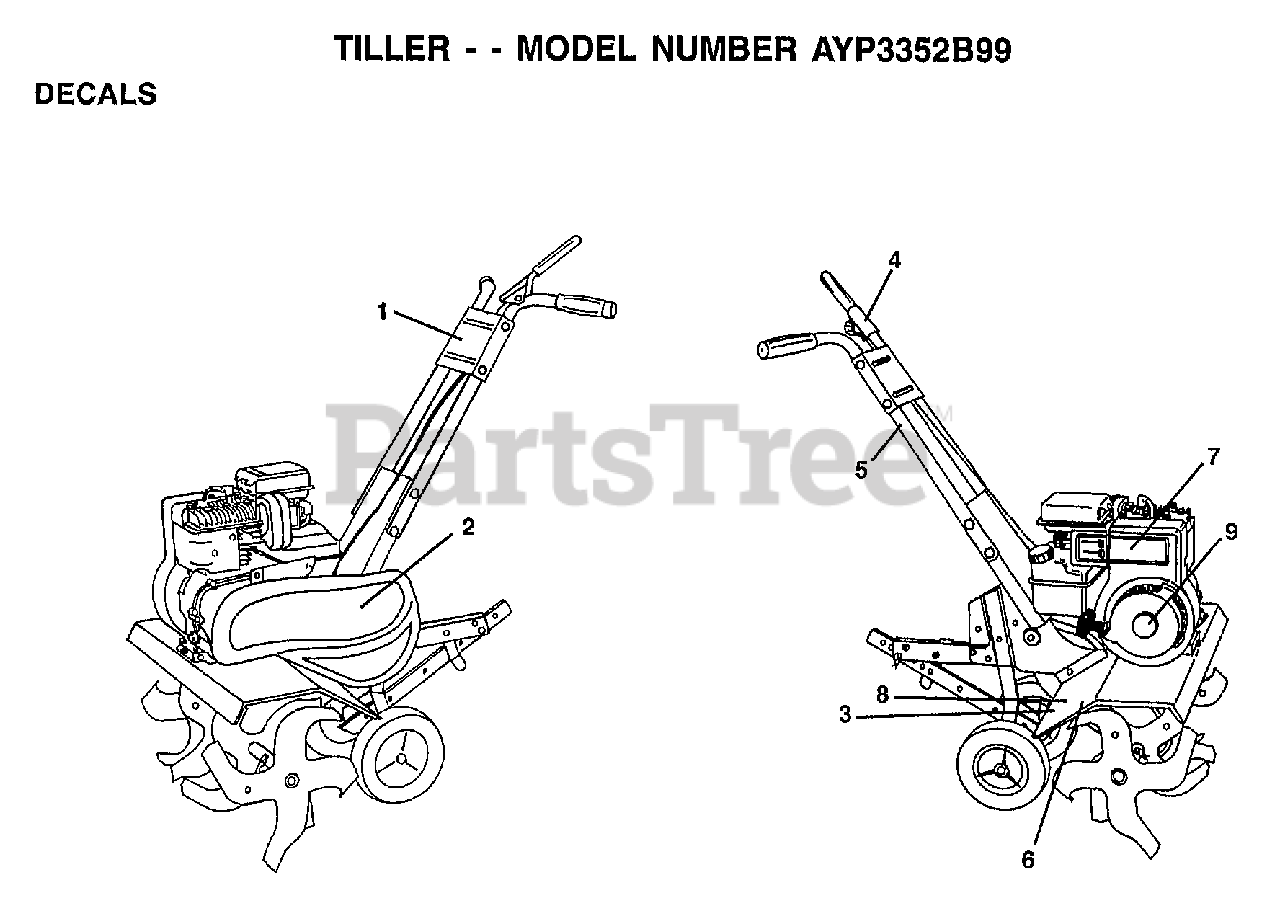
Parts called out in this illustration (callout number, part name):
1	DECAL.CNTRL.PNL.5
2	DECAL, LOGO
4	DECAL TI
5	DECAL TI
6	DECAL.TINE.SHIELD
8	DECAL TI
